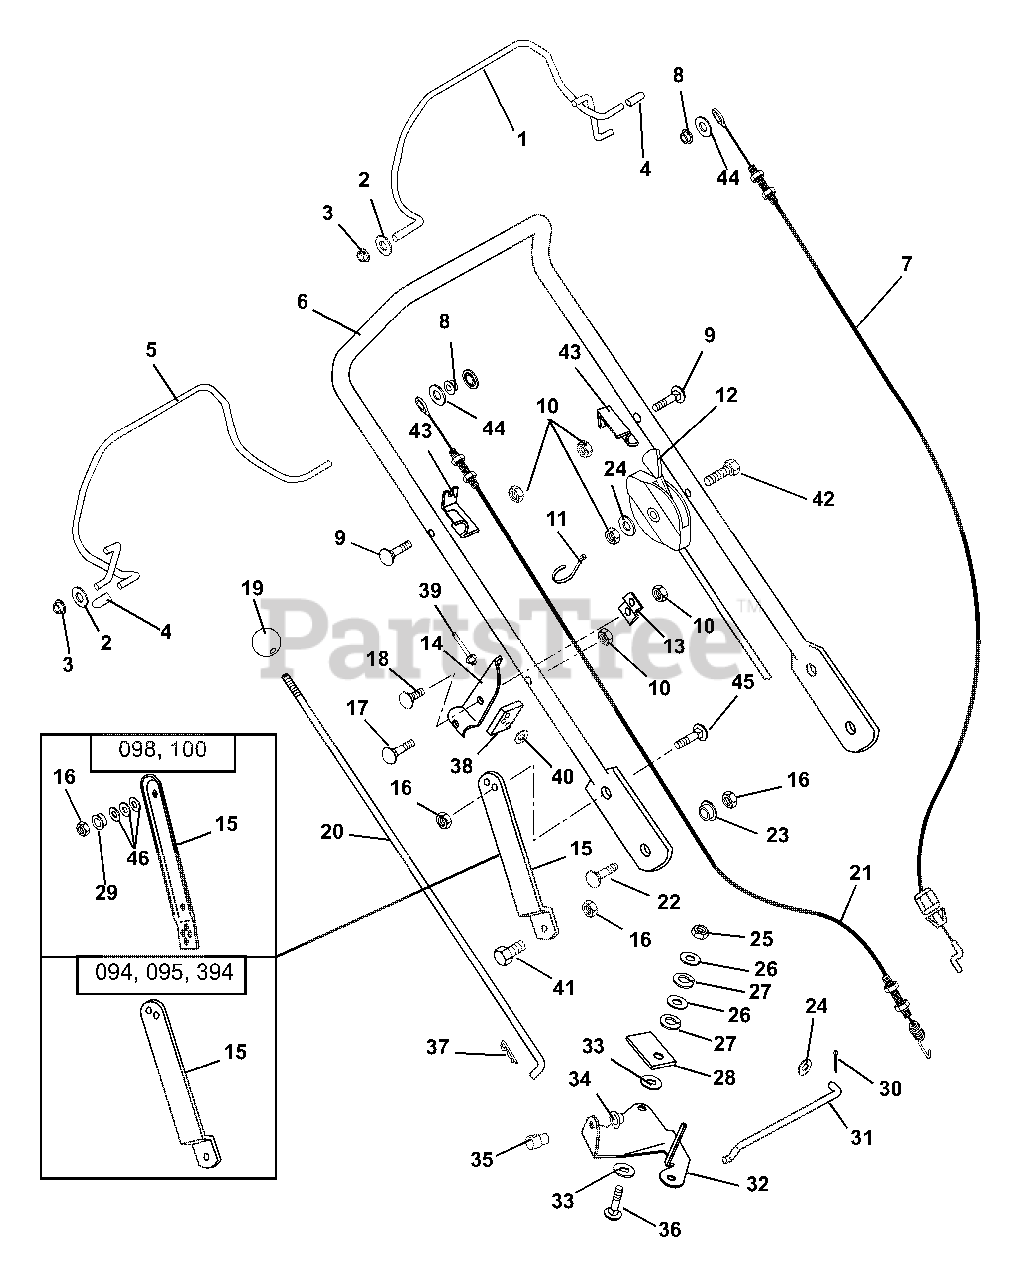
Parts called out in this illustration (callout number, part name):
1	Engine Bail Weldment
2	Washer, Flat Steel .32 x .44 x .44 x .56 (094, 098, 100, 394)
2	Washer, Flat Steel .32 x .44 x .44 x .56 (095)
3	Bushing, Flange .325 x .688 x .56 (094, 098, 100, 394)
3	Bushing, Flange .325 x .688 x .56 (095)
4	Cap, Vinyl .25 I.D. (094, 098, 100, 394)
4	Cap, Vinyl .25 I.D. (095)
5	Traction Bail Weldment (094, 098, 100, 394)
6	Handlebar
7	Cable, Engine
8	Ring, Retaining External .25 x .01 (094, 394)
8	Ring, Retaining External .25 x .01 (095)
8	Nut, Push .25 (98, 100)
9	Bolt, Round Head Square Neck .25-20 x 1.25 (094, 098, 100, 394)
9	Bolt, Round Head Square Neck .25-20 x 1.25 (095)
10	Nut, Locking Center .25-20 (094, 098, 100, 394)
10	Nut, Locking Center .25-20 (095)
11	Cable Tie
12	Control, Throttle - Honda (094, 095, 394)
12	Cable, Lockout Control (100)
13	Brace, Speed Control (094, 098, 100, 394)
14	Bracket, Speed Control (094, 098, 100, 394)
15	Handlebar Bracket (094, 095, 394)
15	Link, Handlebar Adjustment Left Hand (098, 100)
15	Link, Handlebar Adjustment Right Hand (098, 100)
16	Nut, Locking Center .31-18
17	Bolt, Round Head Square Neck .25-20 x 1.38 (094, 098, 100, 394)
18	Bolt, Round Head Square Neck .25-20 x .50 Grade 5 (094, 098, 100, 394)
19	Knob (094, 098, 100, 394)
20	Rod, Speed Control (094, 098, 100, 394)
21	Traction Cable (094, 098, 100, 394)
22	Bolt, Round Head Square Neck .31-18 x 1.00 Grade 5
23	Shoulder Spacer
24	Washer, Flat Steel.281 x .62 x .065 (094, 098, 100, 394)
25	Nut, Locking Center .38-16 (094, 098, 100, 394)
26	Washer, Flat Steel .406 x .812 x .065 (094, 098, 100, 394)
27	Washer, Lock .375 x .115 Heavy (094, 098, 100, 394)
28	Pressure Flange (094, 098, 100, 394)
29	Bushing-Flange .325 x .50 x .513 x .875
30	Pin, Cotter .06 x .50 (094, 098, 100, 394)
31	Shift Link (094, 098, 100, 394)
32	Bell Crank, Speed Control (094, 098, 100, 394)
33	Friction Washer (094, 098, 100, 394)
34	Cap, Rod .375 (094, 098, 100, 394)
35	Swivel (094, 098, 100, 394)
36	Bolt, Round Head Square Neck .38-16 x 1.25 (094, 098, 100, 394)
37	Pin, Hair Internal .08 x .18 x 1.18 (094, 098, 100, 394)
38	Support Pad (094, 098, 100, 394)
39	Rivet .187 x .575 (094, 098, 100, 394)
40	Washer, Flat Steel .219 x .50 x .049 (094, 098, 100, 394)
41	Bolt, Hex .31-18 x .75 Grade 5
42	Bolt-Hex .25-20 x 2.50 Grade 5 (094, 095, 394)
43	Cable Anchor, Left Hand (094, 394)
43	Cable Anchor, Left Hand (095, 098, 100)
44	Washer, Flat Steel .28 x .62 x .065 (094, 098, 100, 394)
44	Washer, Flat Steel .28 x .62 x .065 (095)
45	Bolt, Round Head Square Neck .31-18 x .75 Grade 5
46	Washer, Belleville
